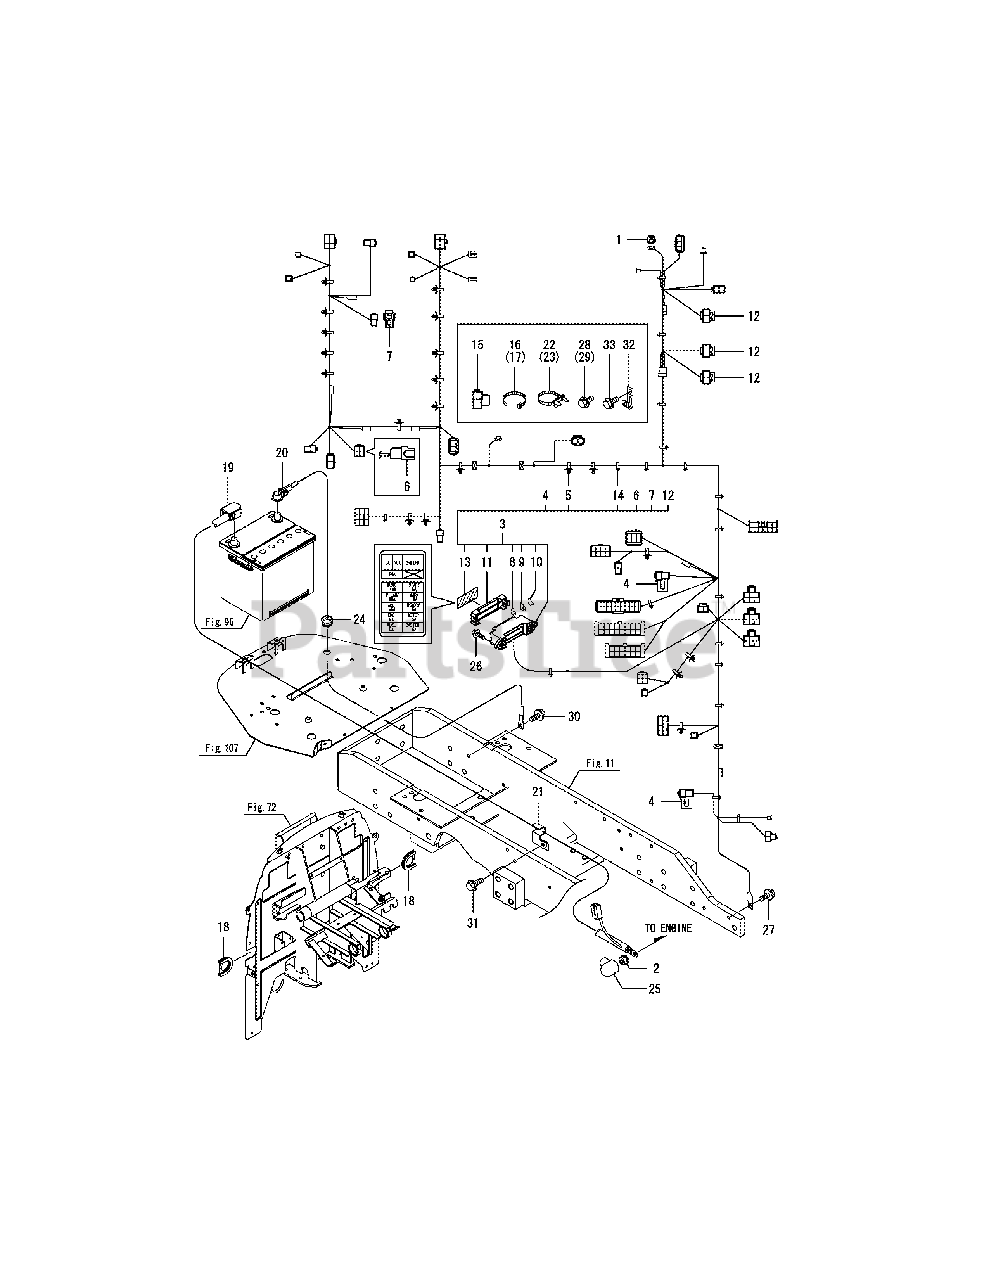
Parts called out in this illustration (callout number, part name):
1	NUT W/WASHER 6
2	NUT W/WASHER 8
3	HARNESS A, ROPS
7	COUPLER,PROTECT
11	COVER, FUSE BOX
12	SLOW BLOW FUSE60A
19	CABLE, BATTERY POSITIVE
20	CABLE, BATTERY NEG
21	CLAMP, B. CABLE
25	COVER, TERMINAL
26	BOLT M 6X 20 PLATED
27	BOLT M 8X 16 PLATED
28	BOLT M 8X 16 PLATED
29	BOLT M 8X 16 PLATED
30	BOLT M 8X 16 PLATED
31	BOLT M 8X 25 PLATED
32	CLAMP, WIRE HARNESS
33	BOLT M 8X 16 PLATED
